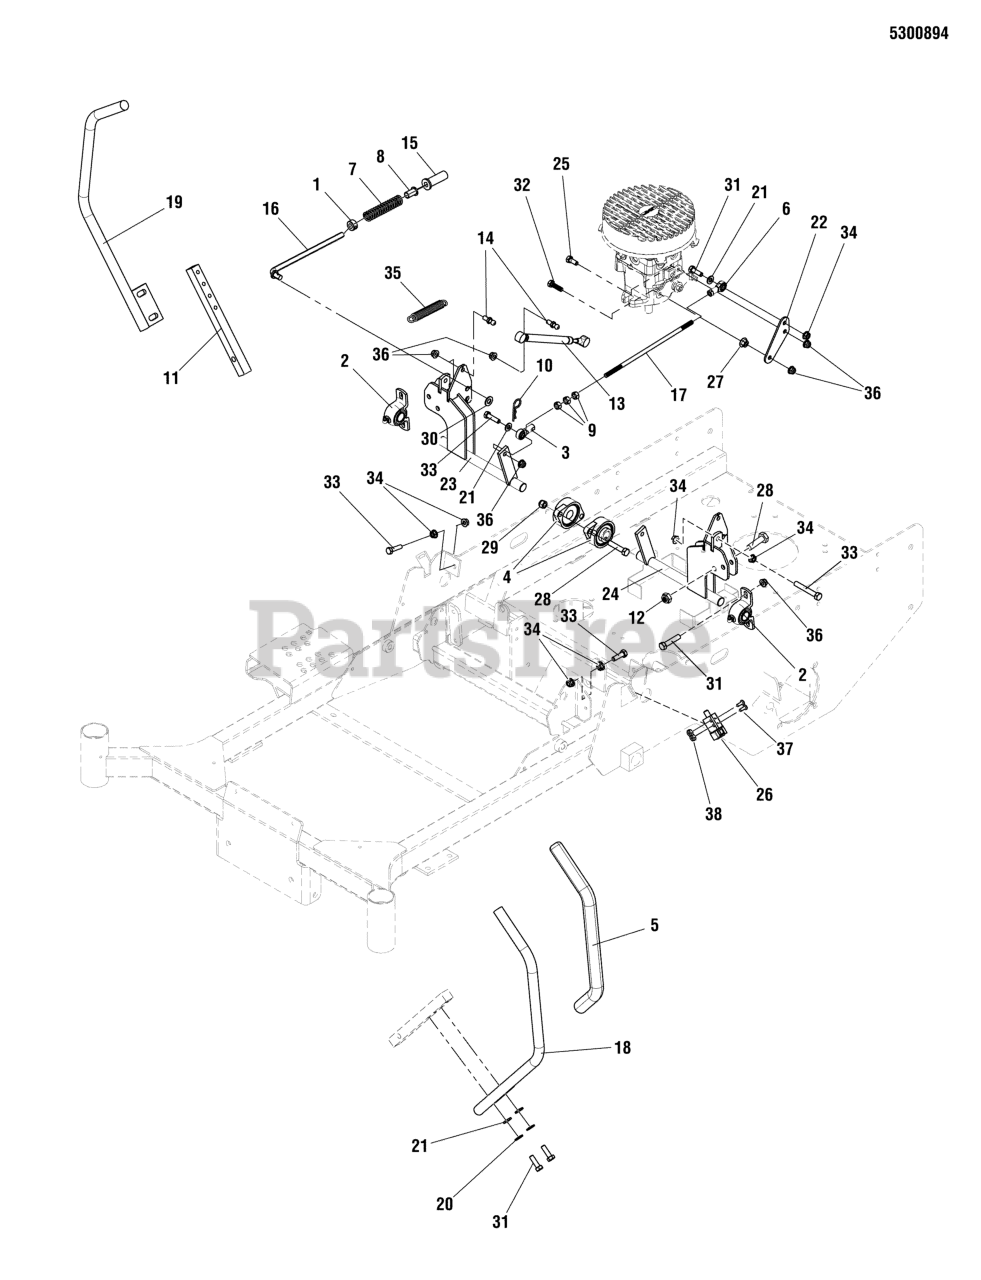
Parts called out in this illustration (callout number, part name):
1	COLLAR, 3/8" SET
2	BEARING, 3/4" PILLOW BLOCK
3	BALL JOINT 5/16-24 RH FEMALE STAMPED STL
4	BEARING, FLANGE
5	GRIP, FOAM, 3/4 ID, 16 LONG
6	BALL JOINT 5/16-24 LH FEMALE STAMPED STL
7	SPRING, REVERSE RETURN
8	BUSHING, NYLON
9	NUT, 5/16-24 HEX
10	PIN, HAIR, .0915 X 1-7/8
11	MOUNT, CONTROL ARM - BLK
12	NUT, 3/8-16 HEX NYLOCK FLANGE
13	DAMPENER, CONTROL,#(P6709/P3610)
14	BALL STUD, 5/16 X .50,# PC-477-2)
15	FLANGED BUSHING, 3/8IDX.63ODX.8125FL
16	ROD, NEUTRAL RETURN
17	ROD, HYDRO LINKAGE
18	WELD, HANDLE MOTION CONTROL, LH - BLK
19	WELD, HANDLE MOTION CONTROL, RH - BLK
20	WASHER, 5/16 LOCK CZ
21	WASHER, 5/16" SAE
22	PLATE, PUMP SUPPORT - RED
23	WELD, CONTROL SHAFT, RH, SNP 2552 - RED
24	WELD, CONTROL SHAFT, LH, SNP 2552 - RED
25	BOLT, 5/16-18 X 3/4 GD5
26	SWITCH, PLUNGER, N.O./N.C.
27	NUT, 5/16-18 HEX SERRATED FLANGE (LARGE)
28	BOLT, 3/8-16 X 1-3/4" GD5 CZ
29	NUT, 3/8-16 HEX NYLON LOCK
30	WASHER, 3/8 SAE
31	BOLT, 5/16-18 X 1 GD5 YZ
32	BOLT, 5/16-18 X 1-1/8 GD5
33	BOLT, 5/16-18 X 1-1/4 GD5 YZ
34	NUT, 5/16-18 HEX SERRATED FLANGE (SMALL)
35	SPRING, EXTENSION
36	NUT, 5/16-18 HEX NYLOCK FLANGE
37	SCREW, #10-24 X 1/2 ROUND PHILLIPS
38	NUT, #10-24 HEX
